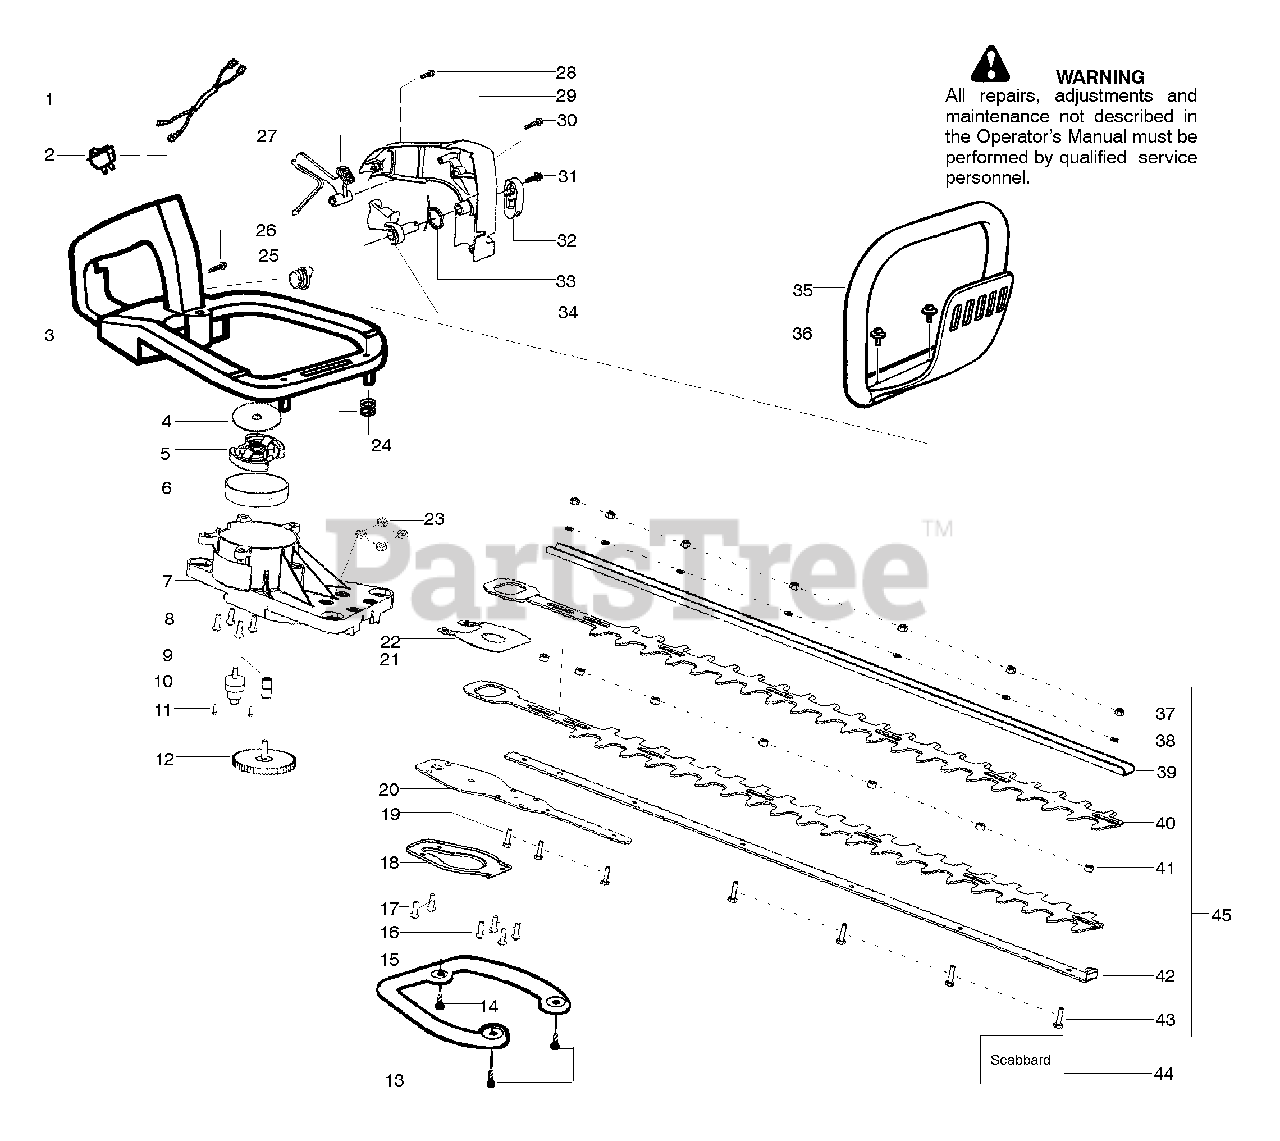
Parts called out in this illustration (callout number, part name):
1	Assy-Leadwire/Switch
2	Switch-Ignition
3	Assy-Rear Handle & Tank
4	Washer-Clutch
5	Kit-Clutch Assy.
6	Assy-Drum
7	Assy-Gear Box
9	Bearing-Gear
10	Assy-Pinion
11	Screw
12	Assy-Gear
15	Plate-Isolator
18	Cover-Gear Box Plate
20	Plate-Bearing
21	Spacer (Qty. 1)
22	Spacer-Plate
25	Assy-Fuel Cap
27	Lockout-Throttle
29	Kit-Handle Cover
32	Lever-Trigger
33	Spring-Trigger
35	Handle-Front
37	Nut (Qty. 7)
38	Lockwasher (Qty. 7)
40	Blade-recipricating (Qty. 2)
41	Spacer (Qty. 6)
42	Bar-Bottom
43	Screw (Qty. 4)
44	Scabbard-Blade
45	Kit-Blade Assy.
